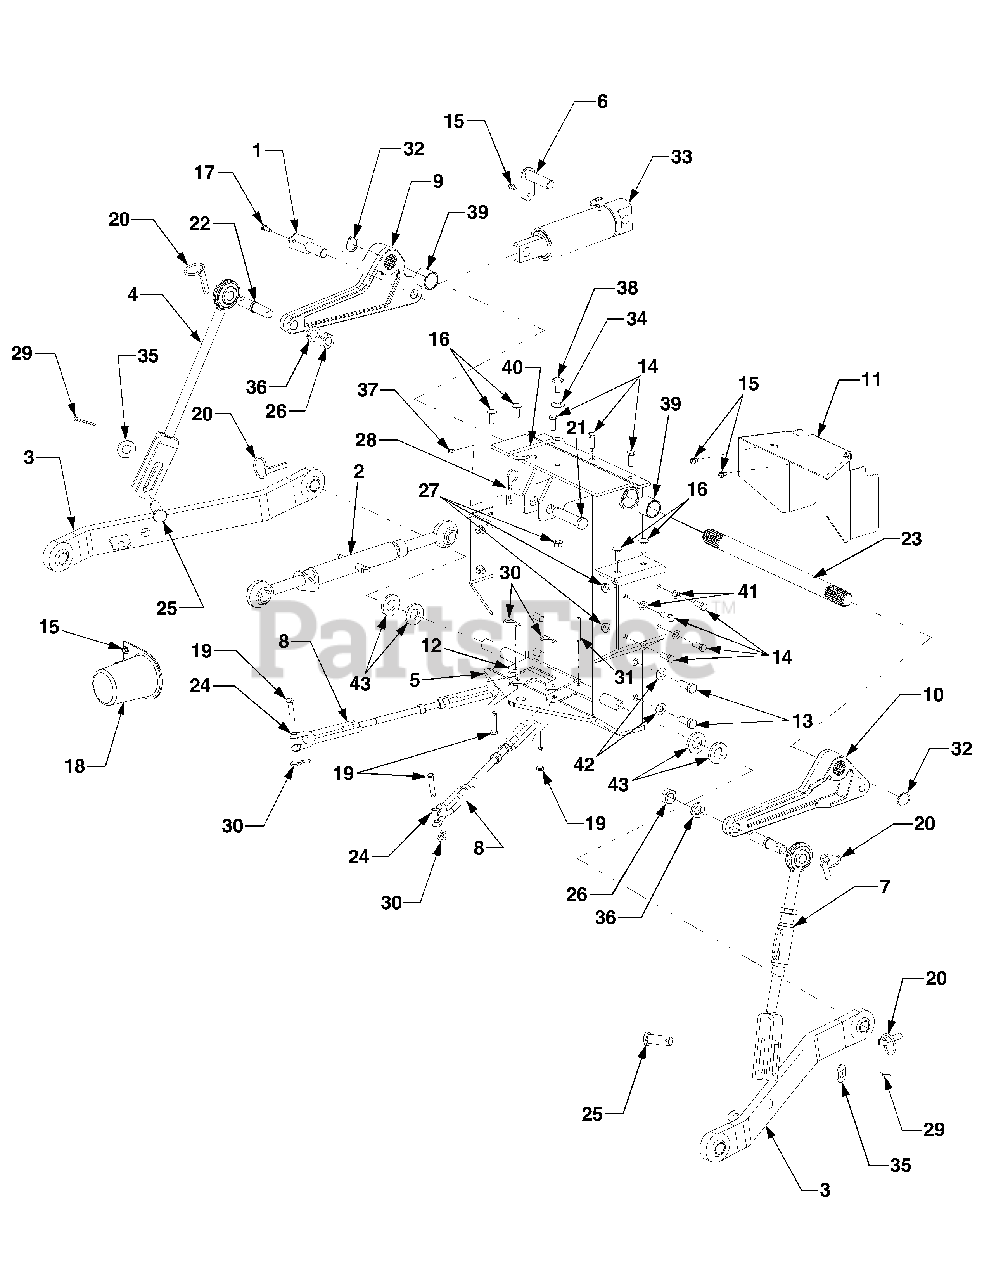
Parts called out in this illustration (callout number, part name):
1	Plate, Cylinder Mounting
2	Link Assembly, Upper
3	Link, Lower
4	Link, Fixed Lift
5	Bracket Assembly, Rear Hitch
6	Plate, Cylinder Mounting
7	Link, Adjustable Lift
7	Link Rod RH Thrd.
7	Link Rod LH Thrd.
7	Turnbuckle
7	Jam Nut, M20 x 2.5 RH
8	Chain Assembly, Check
8	Chain Link RH Thrd.
8	Chain Link Lh Thrd.
8	Chain Rod, Adjust.
9	Arm, Hitch Lift - LH
10	Arm, Hitch Lift - RH
11	Shield, PTO Shaft
11	Graphic, Warning
12	Bracket, Chain Mounting
13	Screw, Hex Cap Lock, 1/2-13 x 1.25 GR5
14	Screw, Hex Cap, 3/8-16 x 1.0 GR5
15	Screw, Hex Wash. Hd. Tapp 1/4-20 x .5
16	Screw, Carriage, 3/8-16 x 1.0
17	Screw, Hex Cap, 1/4-20 x .75 GR5
18	Cover, PTO Shaft
19	Pin, Clevis, .372 x 1.79
20	Pin, Klik
21	Pin, Clevis, 19mm x 84mm
22	Pin, Hitch, .75 OD
23	Shaft, Hitch Rock
24	Clevis, Chain
25	Pin, Clevis, .75 x 1.938
26	Nut, Hex Jam, 3/4-10 GR5
27	Nut, Hex Flange Lock, 3/8-16 GRF
28	Pin, Internal Cotter
29	Pin, Cotter, 3/16 x 1.5
30	Pin, Internal Cotter
31	Pin, Spirol, 1/4 x 2.0
32	Ring, Retaining
33	Cylinder, Lift
34	Washer, Belleville, .51 x 1.14 x .04
35	Washer, Flat, .76 x 1.5 x .12
36	Washer, Lock, 3/4
37	Fitting, Lube, 3/16 Drive
38	Screw, Shoulder, 3/8-16
39	Bearing, Sleeve, 1.25 x 1.50 x 1.25
40	Rod, Top Link Hanger
41	Washer, Flat, .375 x .738 x .063
42	Washer, Flat, .51 x 1.0 x .06
